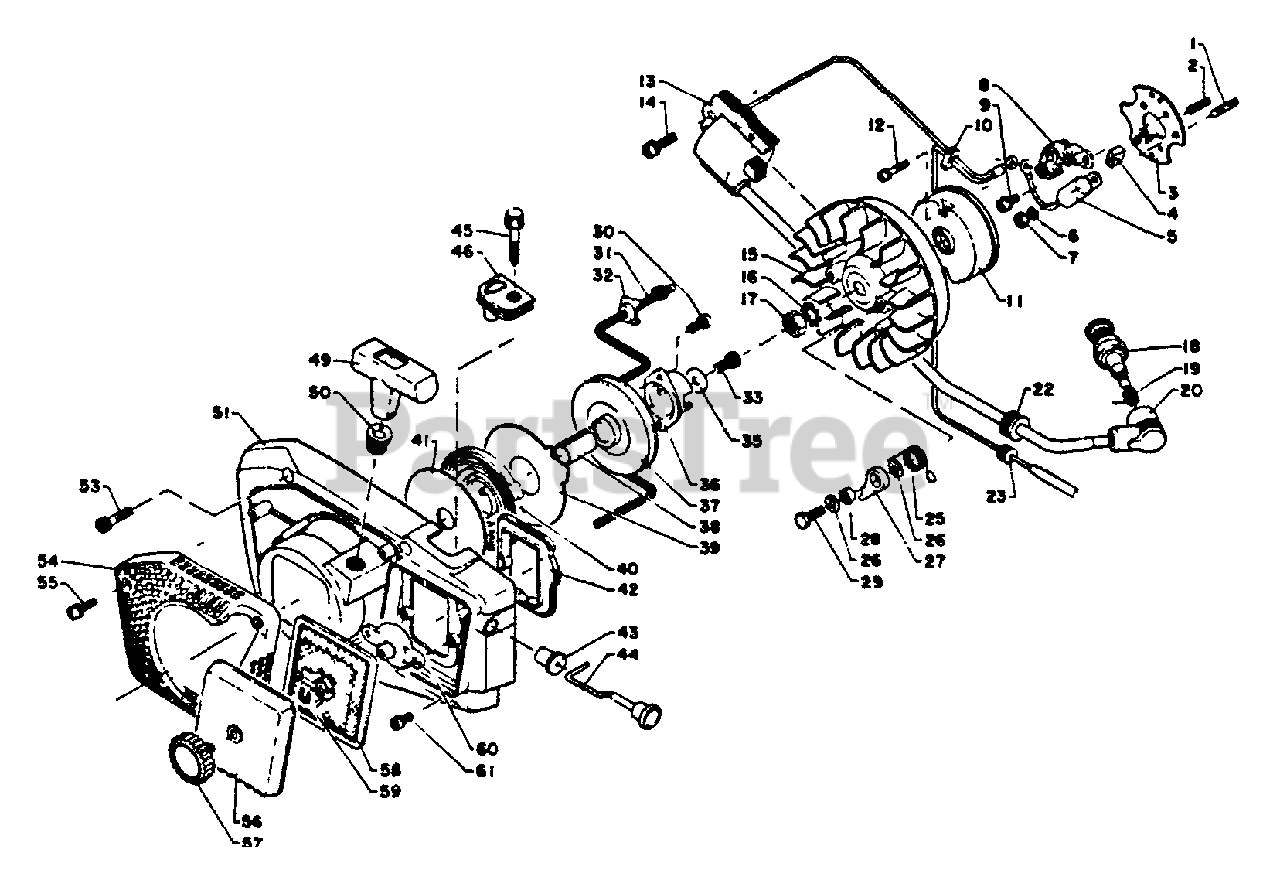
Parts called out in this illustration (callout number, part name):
1	STUD
2	STUD
3	PLATE, STATOR
4	PAD, FOAM
5	CONDENSER
6	LOCKWASHER - 4
8	CONTACT POINT SET
9	SCREW - 4X8
10	GROMMET
11	COVER, BREAKER
12	SCREW - 3X18
13	COIL, IGNITION
14	SCREW - 5X20
15	FLYWHEEL
16	LOCKWASHER - 8
18	SPARK PLUG -- BM-6A
19	TERMINAL, SPARK PLUG CAP
20	CAP, SPARK PLUG
22	GROMMET
23	GROMMET
25	SPRING, RETURN
26	WASHER - 5
27	PAWL, STARTER
29	BOLT - 5X18
30	SCREW - 4X10
31	ROPE, STARTER
32	RETAINER, ROPE
33	SCREW - 5X14
35	WASHER - 5
36	CATCHER, PAWL
37	REEL, ROPE
39	PLATE, STARTER
40	SPRING, REWIND
41	PLATE, STARTER
42	GASKET, CARBURETOR CASE
43	GROMMET
44	ROD, CHOKE
45	SCREW, IDLE ADJUST
46	GROMMET
49	GRIP, STARTER
50	GUIDE, ROPE
51	CASE, STARTER
53	SCREW - 5X20
54	FILTER, DEBRIS
55	SCREW - 4X12
56	COVER, AIR FILTER
57	THUMBSCREW
58	FILTER, AIR
59	RING, RETAINING - 4
60	PLATE, PREVENT
61	SCREW - 4X8
62	RING, RETAINING
